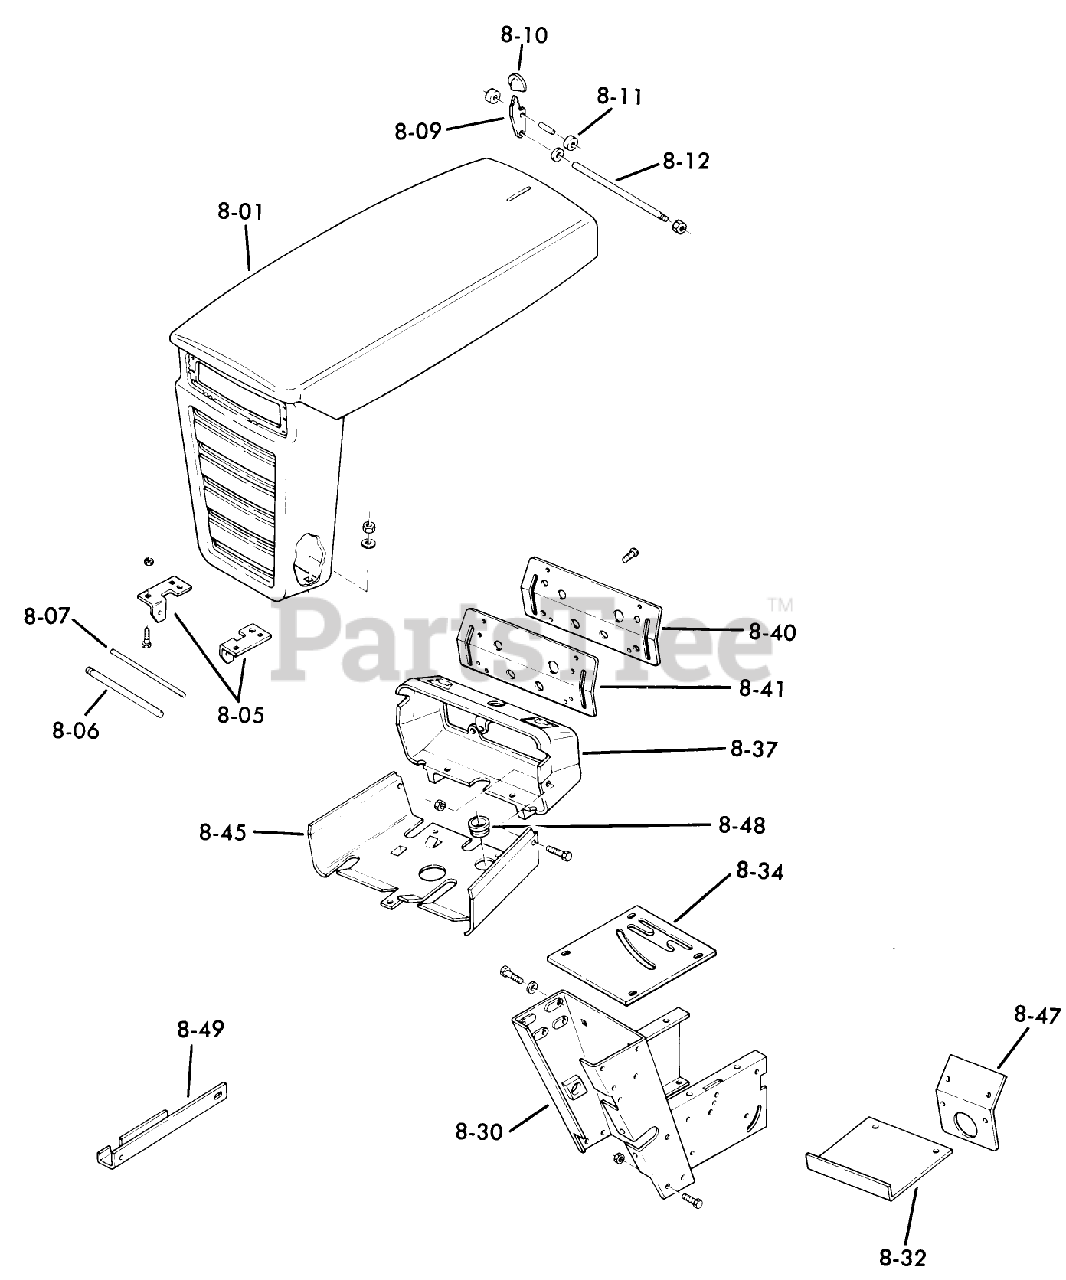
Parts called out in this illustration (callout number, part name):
8-06	GRILL PIVOT ROD
8-06A	ROD-HOOD STOP
8-07	GROMMET
8-09	LEVER HOOD LATCH
8-09	SPIROL PIN
8-10	KNOB
8-32	Cover-Dust
8-40	Dash Panel (B-60)
8-45	Screw
8-47	Plate Cover Hoodstand
